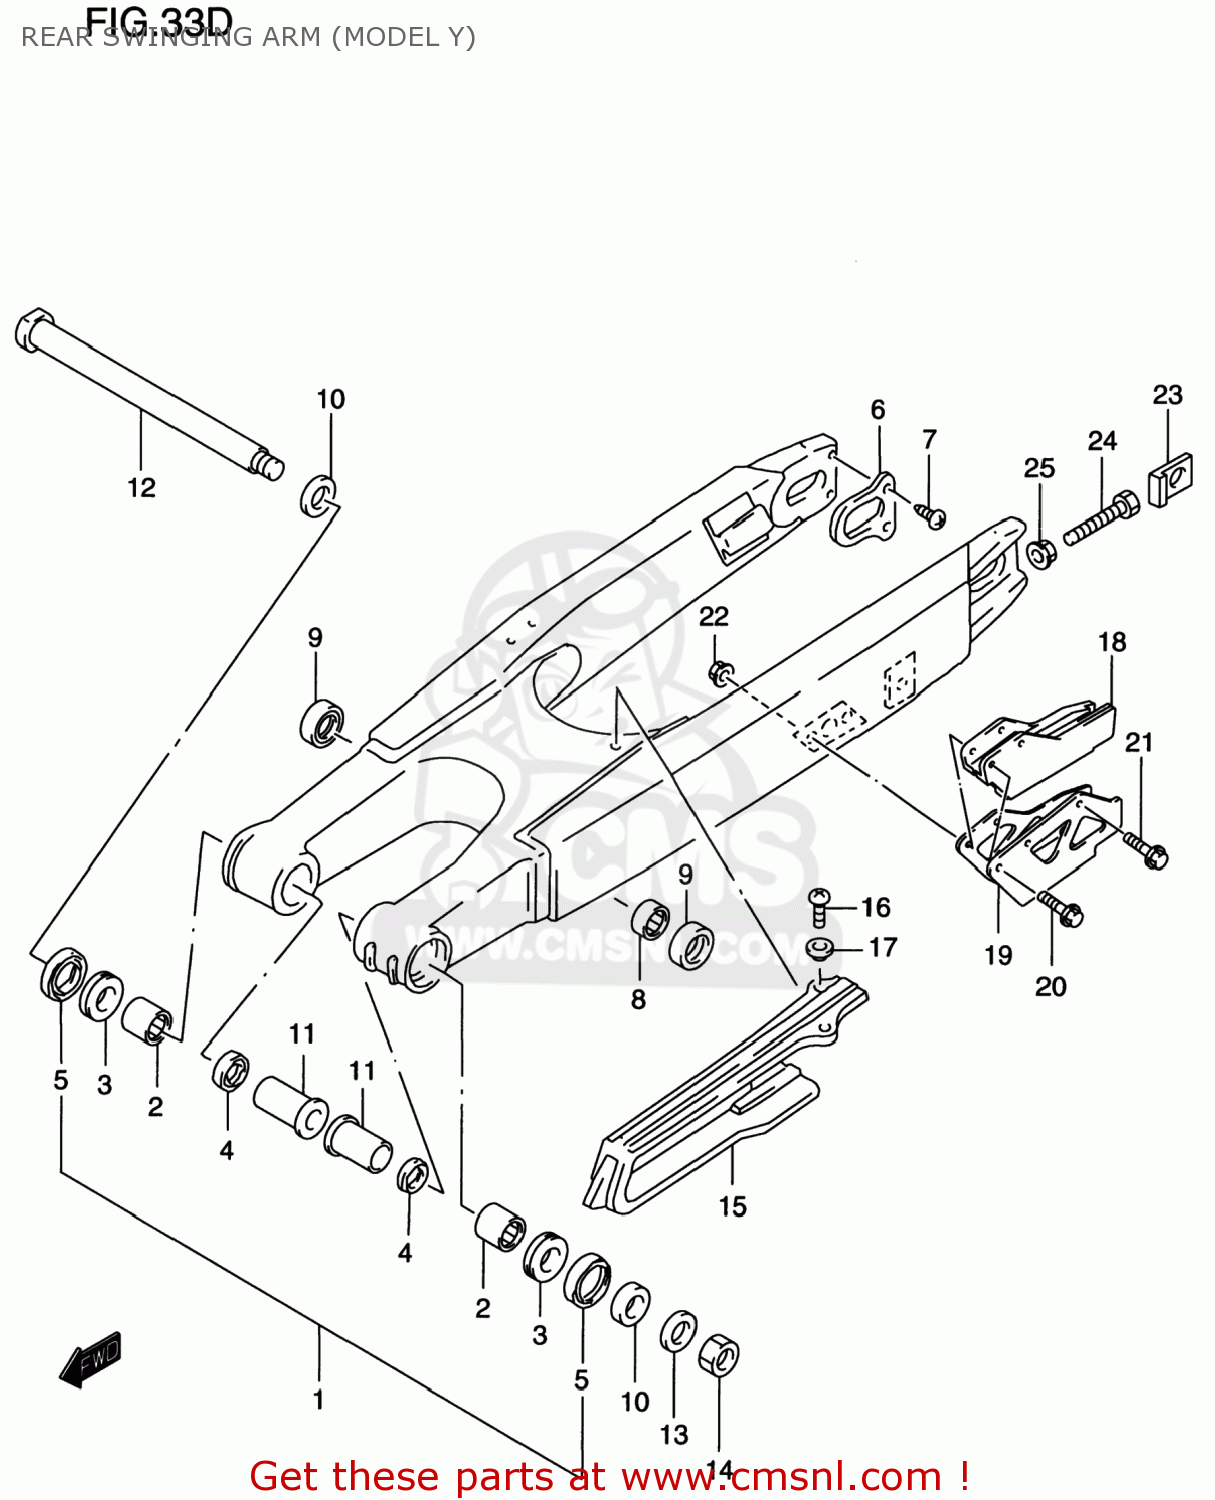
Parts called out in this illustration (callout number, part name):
1	SWING ARM ASSEMBLY,REAR
2	BEARING(22X29X30)
3	BEARING(22X35X2)
4	SEAL,OIL(22X29X4)
5	SEAL,RR SWGARM PIVOT OUTER
6	PLATE,RR SWING ARM RR
7	SCREW,UPPER
8	BEARING(20X27X15)
9	SEAL,CUSHION LEVER DUST
10	SPACER,RR SWGARM PIVOT OUTER
11	SPACER,SWGARM PIVOT INNER
12	SHAFT,RR SWINGINGARM PIVOT
13	WASHER, FIXED DRIVE FACE
14	NUT
15	BUFFER,CHAIN TOUCH DEFLECTOR
16	SCREW
17	WASHER
18	GUIDE,CHAIN
19	PLATE,CHAIN GUIDE
20	BOLT
21	BOLT
22	NUT
23	WASHER,CHAIN ADJUSTER
24	BOLT(8X50)
25	NUT
